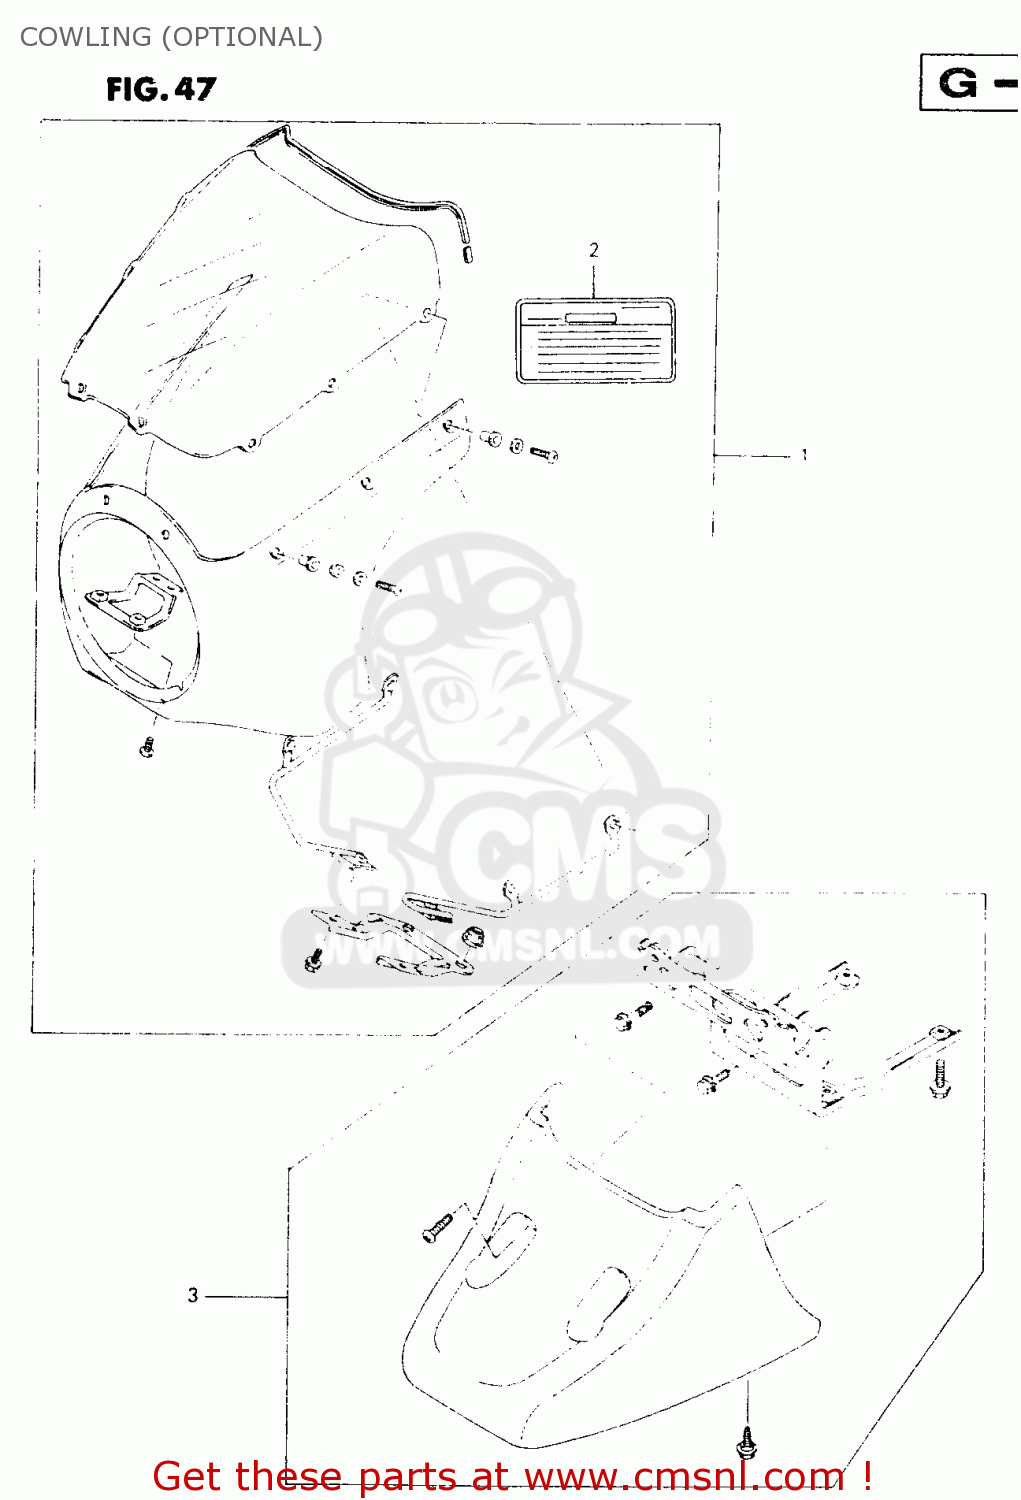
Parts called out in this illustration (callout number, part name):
1	FAIRING SET,BL
2	LABEL (WARNING SCREEN)
3	SPOILER,BLACK
